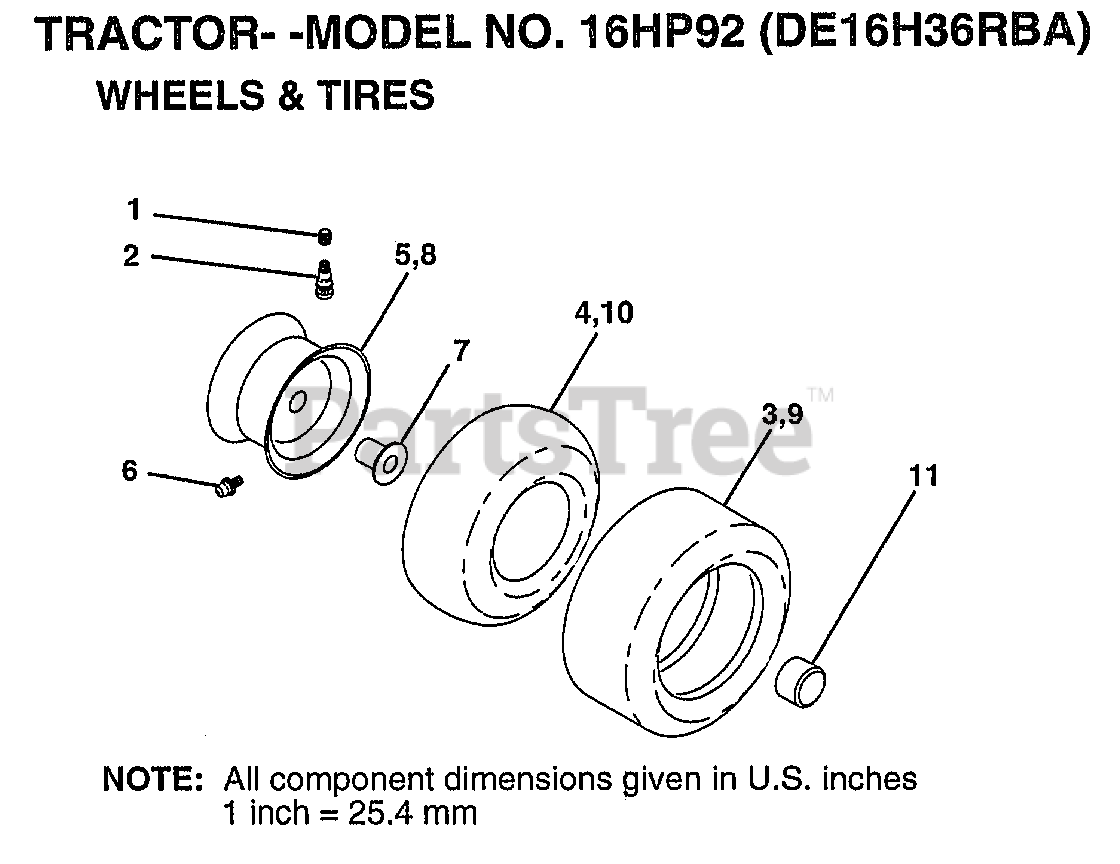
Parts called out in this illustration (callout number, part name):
1	VALVE CAP
2	VALVE STEM LT
4	TUBE.5.3/4.5/6
5	"RIM,FRT T"
6	FITTING LT
7	"FLANGE, BEARING"
8	"RIM 8"""
9	TIRE.20X8-8
10	TUBE.18X9.5-8
11	HUB CAP
